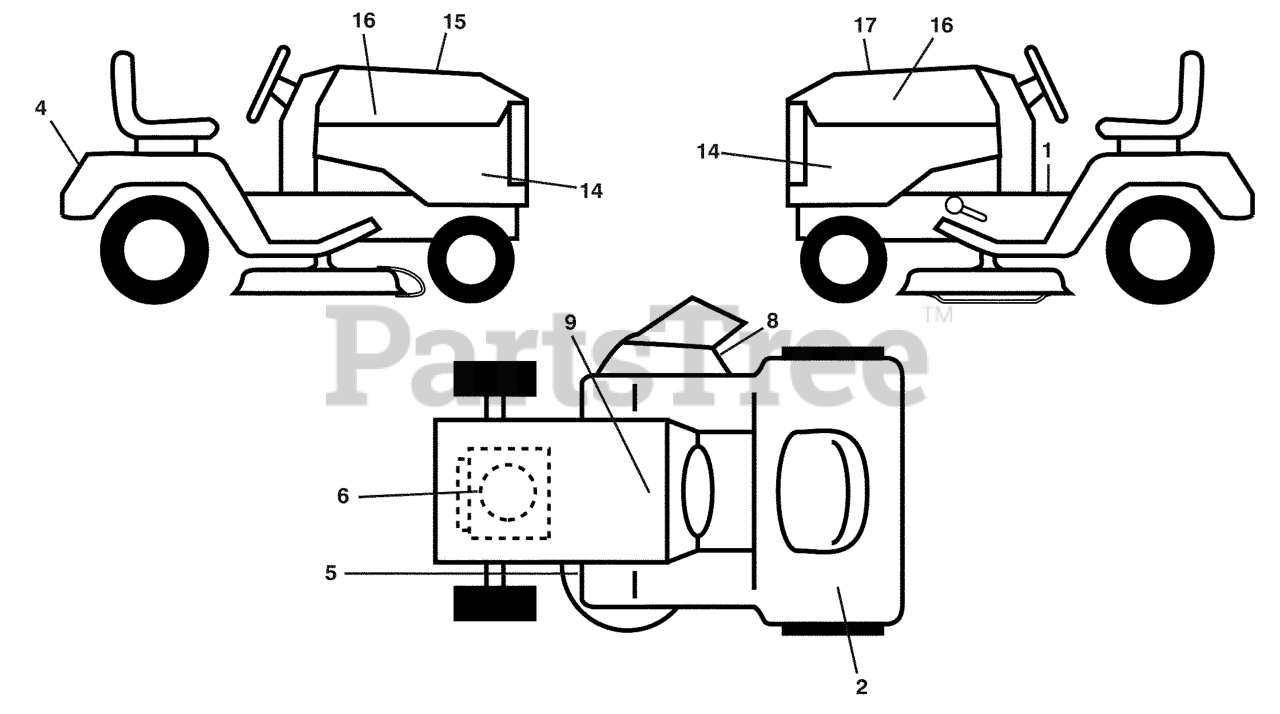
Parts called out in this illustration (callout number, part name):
1	DECAL.WARN.START.INSTRUCTIONS
2	DECAL,ETHANOL E85 WARNING
4	DECAL.FENDER
5	DECAL.MOWER
6	DECAL, ENG. HP
8	DECAL.MOWER.SCH.48/54
9	DECAL BTRY SYMBOLS
14	DECAL, PANEL SIDE
15	DECAL HOOD CUST. RESP.
16	DECAL.HOOD.LOGO.ORANGE.HUSQVAR
17	DECAL.RPL.BS.22INTK/HY/48E.TLT
